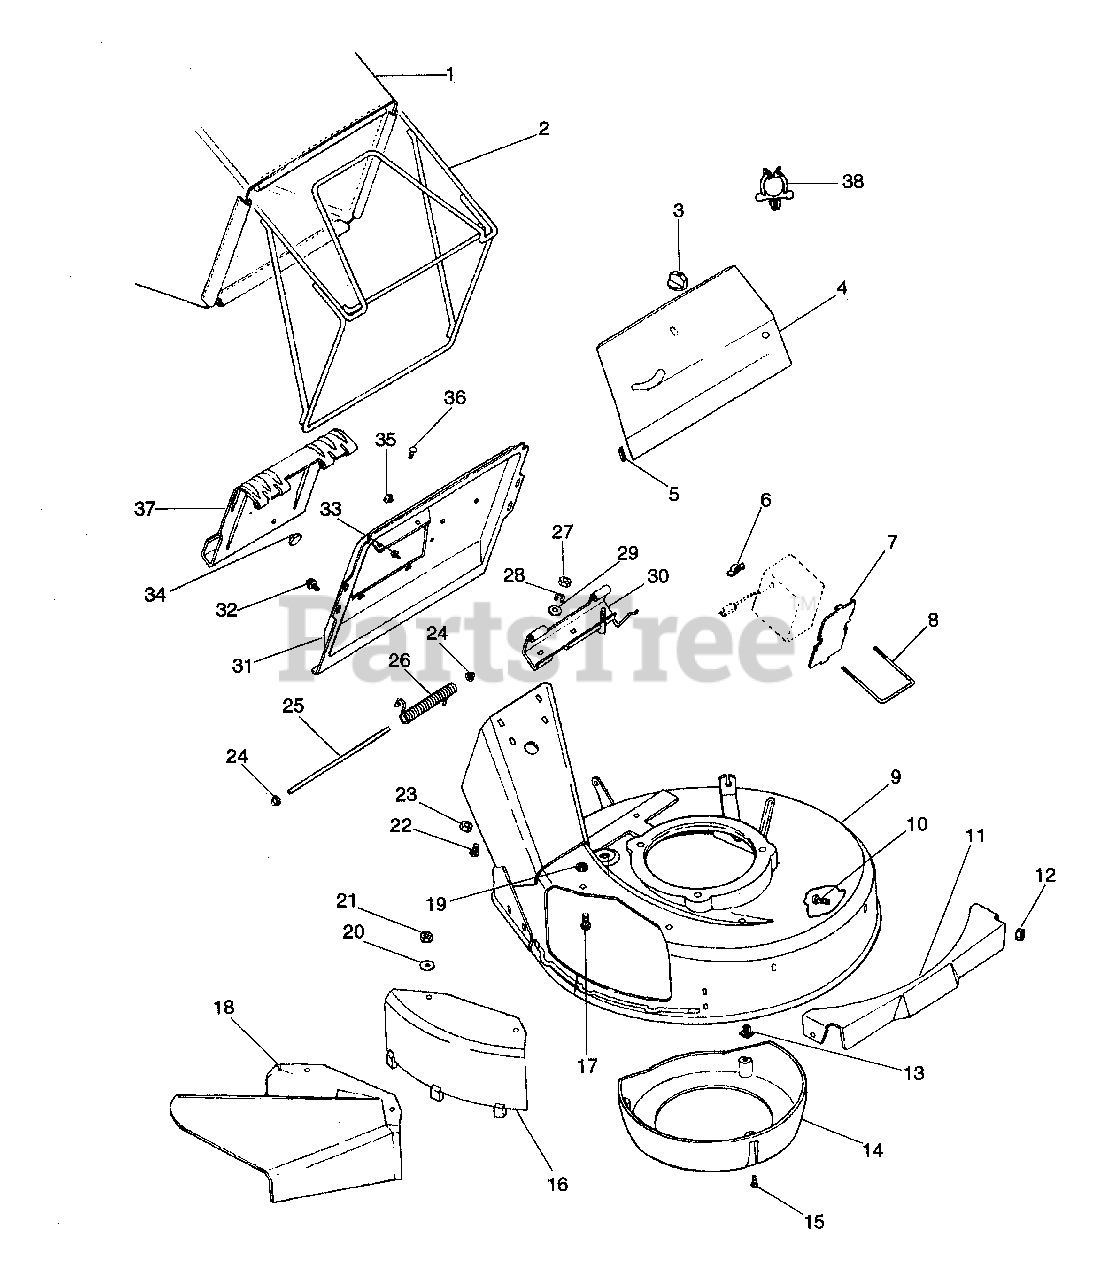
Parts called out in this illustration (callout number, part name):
1	BAG,CONSUMER BLACK 15 OZ/YD2
1	BAG,COMMERCIAL WHITE
2	BAGGER FRAME
3	WING - NUT
4	DRIVE COVER
5	TRIM BUMPER
6	NUT-WING 8-32
7	HOLD DOWN PLATE
8	U-BOLT
9	MOWER PAN W/DECALS PUSH
9	MOWER PAN W/DECALS SP/COMM
9	MOWER PAN W/DECALS BBC
10	BLT-RDHDSQSHNK .31-18X.50 YZ
11	FRONT PANEL
12	NUT-LK .312-18 GR A PL
13	PLASTIC GROMMET
14	CENTER BAFFLE
15	SCR-TAP 10-16X.62 SLPH PL AB
16	SIDE DISCHARGE COVER
17	BLT-RDHDSQNK .31-18X.75 SHT PL
18	DISCHARGE CHUTE
19	NUT-PUSH .312
20	WSHR-FL-STL .38X.875X.083 PL
21	NUT-LK-NYL.312-18 PL
22	BLT-RDHDSQNK .25-20X.62 PL
23	NUT-LK-FLG .250-20 PL
24	PUSH NUT, .25
25	DOOR PIN
26	SG-TORS .120X.68X3.09
27	NUT-HEX .250-20 PL
28	WSHR-LK .250X.077 HVY PL
29	WSHR-FL-STL .380X.875X.179 PL
30	HINGE BASE
30	HINGE BASE WELDMENT
31	CATCHER PLATE
32	SCR-TAP 12-24X.50 HWH PL TR
33	SCR-TAP 10-24X.375 TORX PHD
34	BUTTON BUMPER
36	@BLT-RHDSSQNK .25-20X.38 G2YZ
37	CATCHER PLATE DOOR
38	SNAP-IN CLIP
